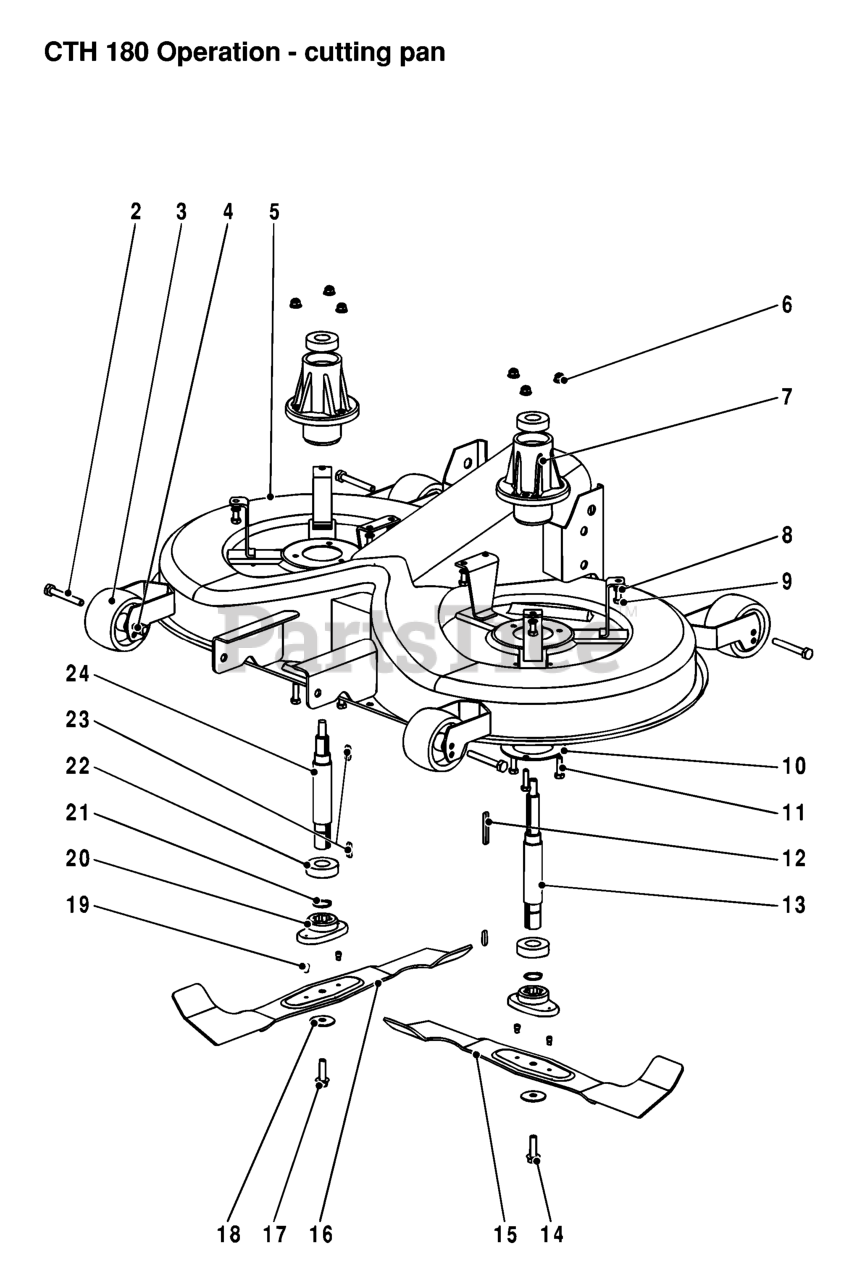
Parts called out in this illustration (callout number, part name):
5	COVER CPL.
21	RETAINING RING
22	BALL BEARING
